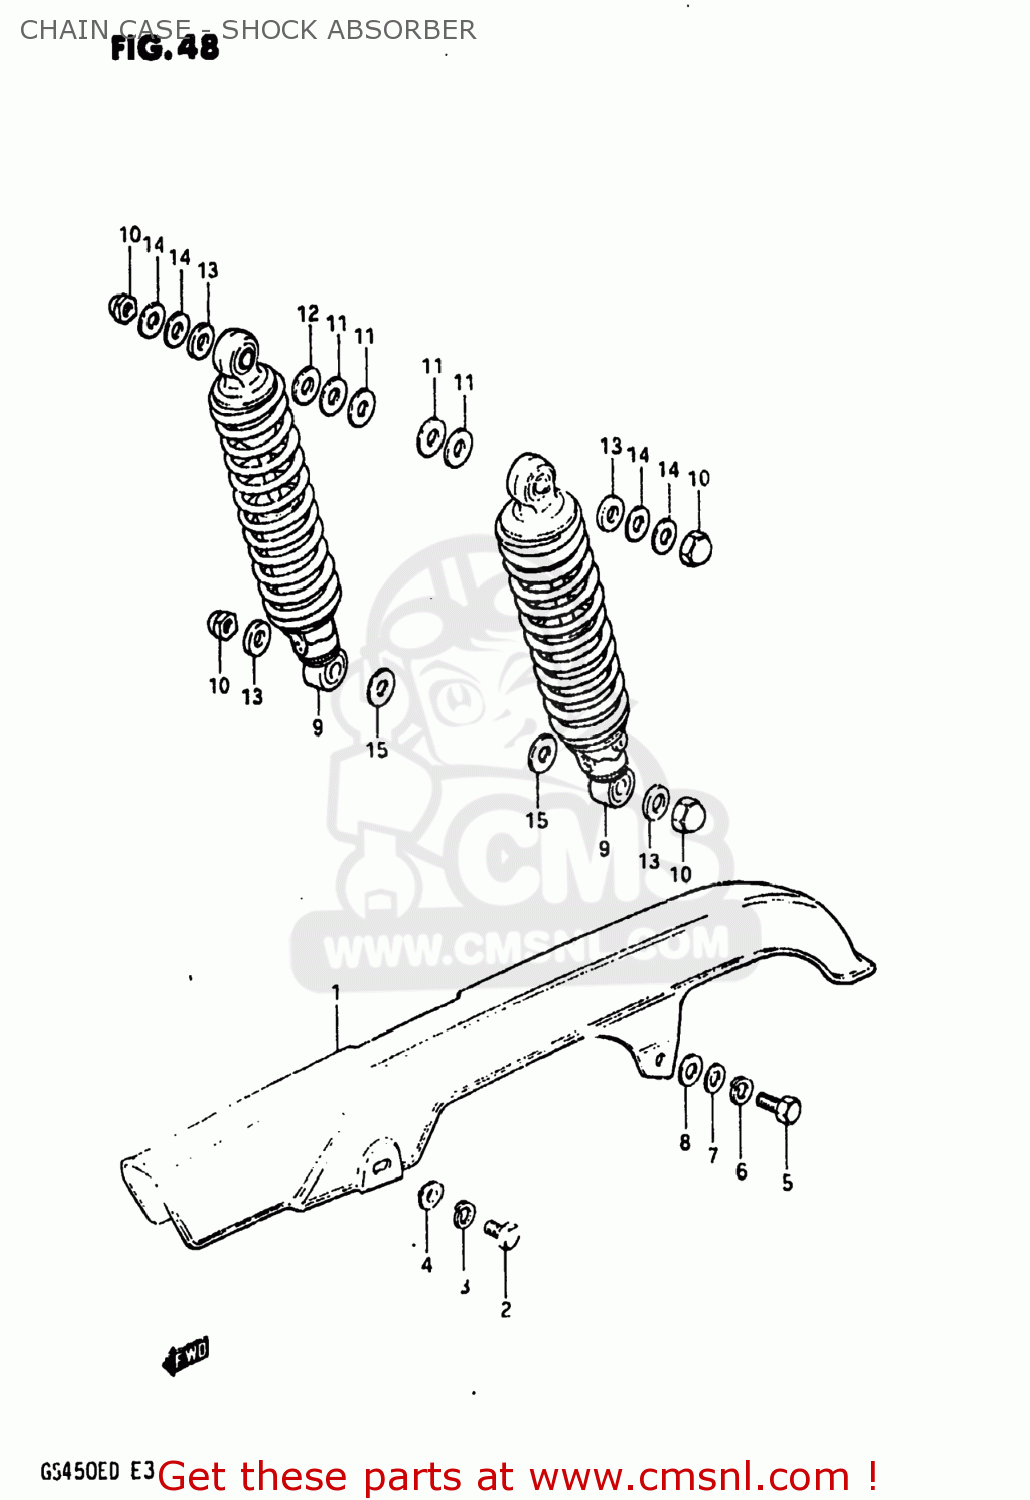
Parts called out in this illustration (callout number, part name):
1	CASE,CHAIN
2	BOLT
3	LOCK WASHER
4	WASHER,LOCK
5	BOLT
6	LOCK WASHER
7	WASHER
8	WASHER
9	ABSORBER ASSEMBLY,REAR SHOCK
10	NUT, LOWER LH
11	WASHER
12	WASHER (12.5X24X3.2)
13	WASHER
14	WASHER(10.5X24X3.2)
15	WASHER (12.5X24X1.6)
